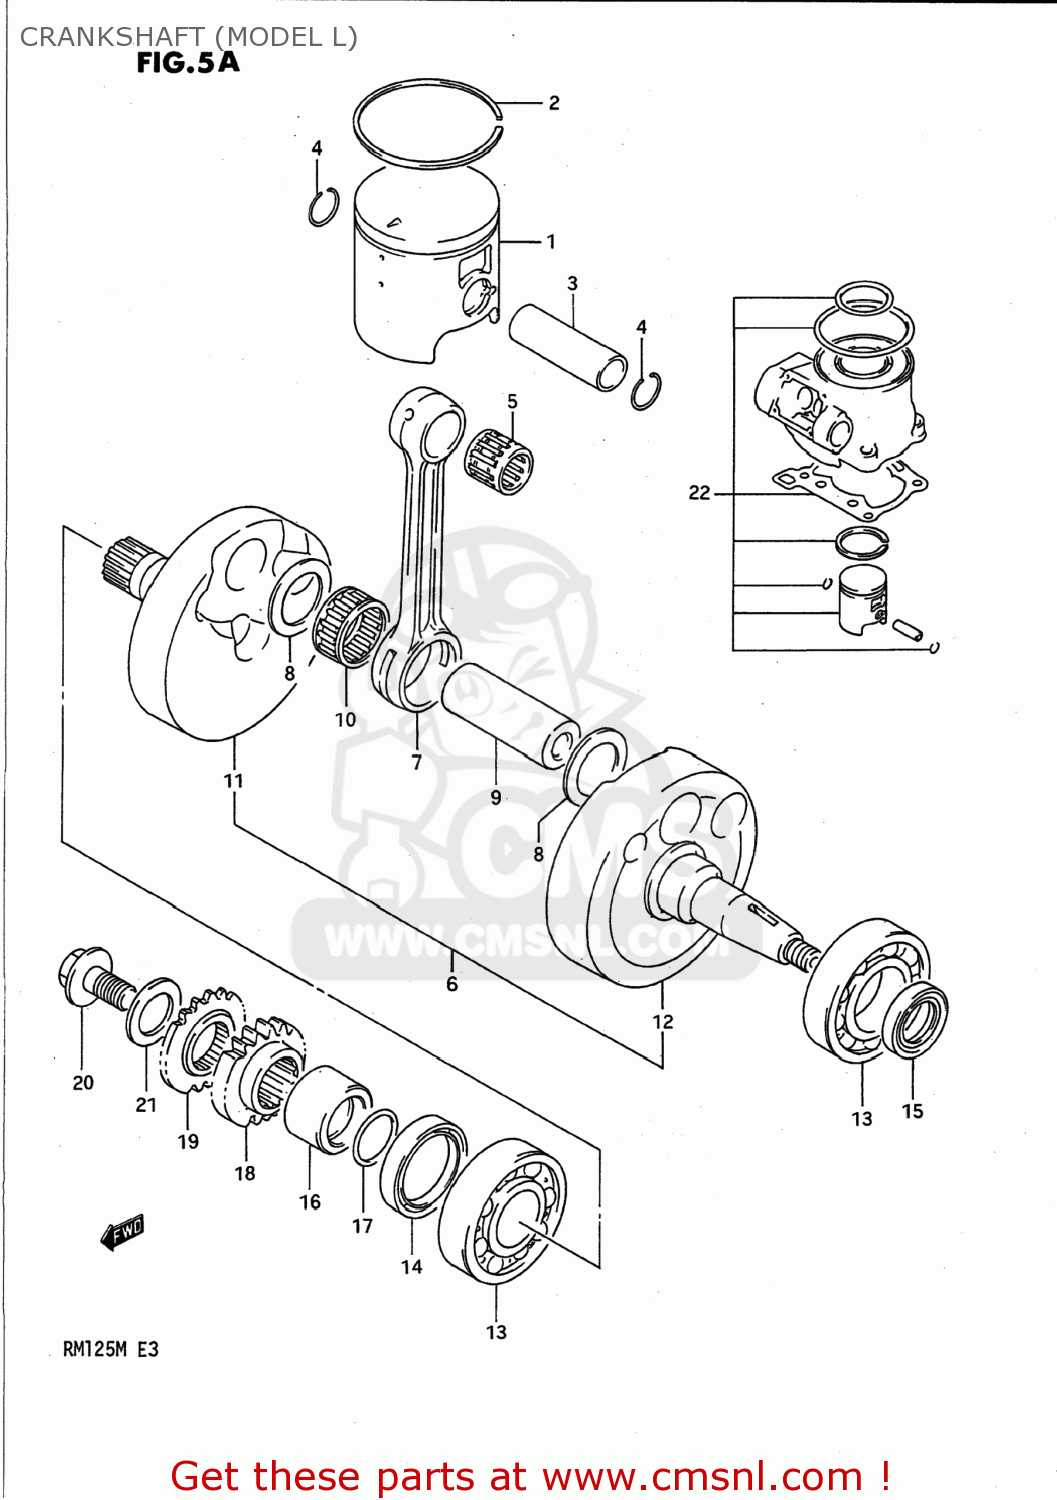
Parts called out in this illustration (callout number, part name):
1	PISTON
2	RING,PISTON
3	PIN,PISTON
4	CIRCLIP
5	BEARING(15X19X20)
6	CRANKSHAFT ASSEMBLY
7	ROD,CONNECTING
8	WASHER
9	PIN,CRANK
10	ROLLER BEARING (22X28X1
11	CRANKSHAFT
12	CRANKSHAFT,LEFT
13	BEARING
14	OIL SEAL
15	SEAL,OIL(18X30X6)
16	SPACER,PRIMARY DRIVE GEAR
17	O RING(D:2.4,ID:19.8)
18	GEAR,PRIMARY DRIVEN
19	GEAR, GOVERNOR DRIVE (NT:19)
20	BOLT,PRIMARY DRIVE GEAR
21	WASHER
22	PISTON SET
